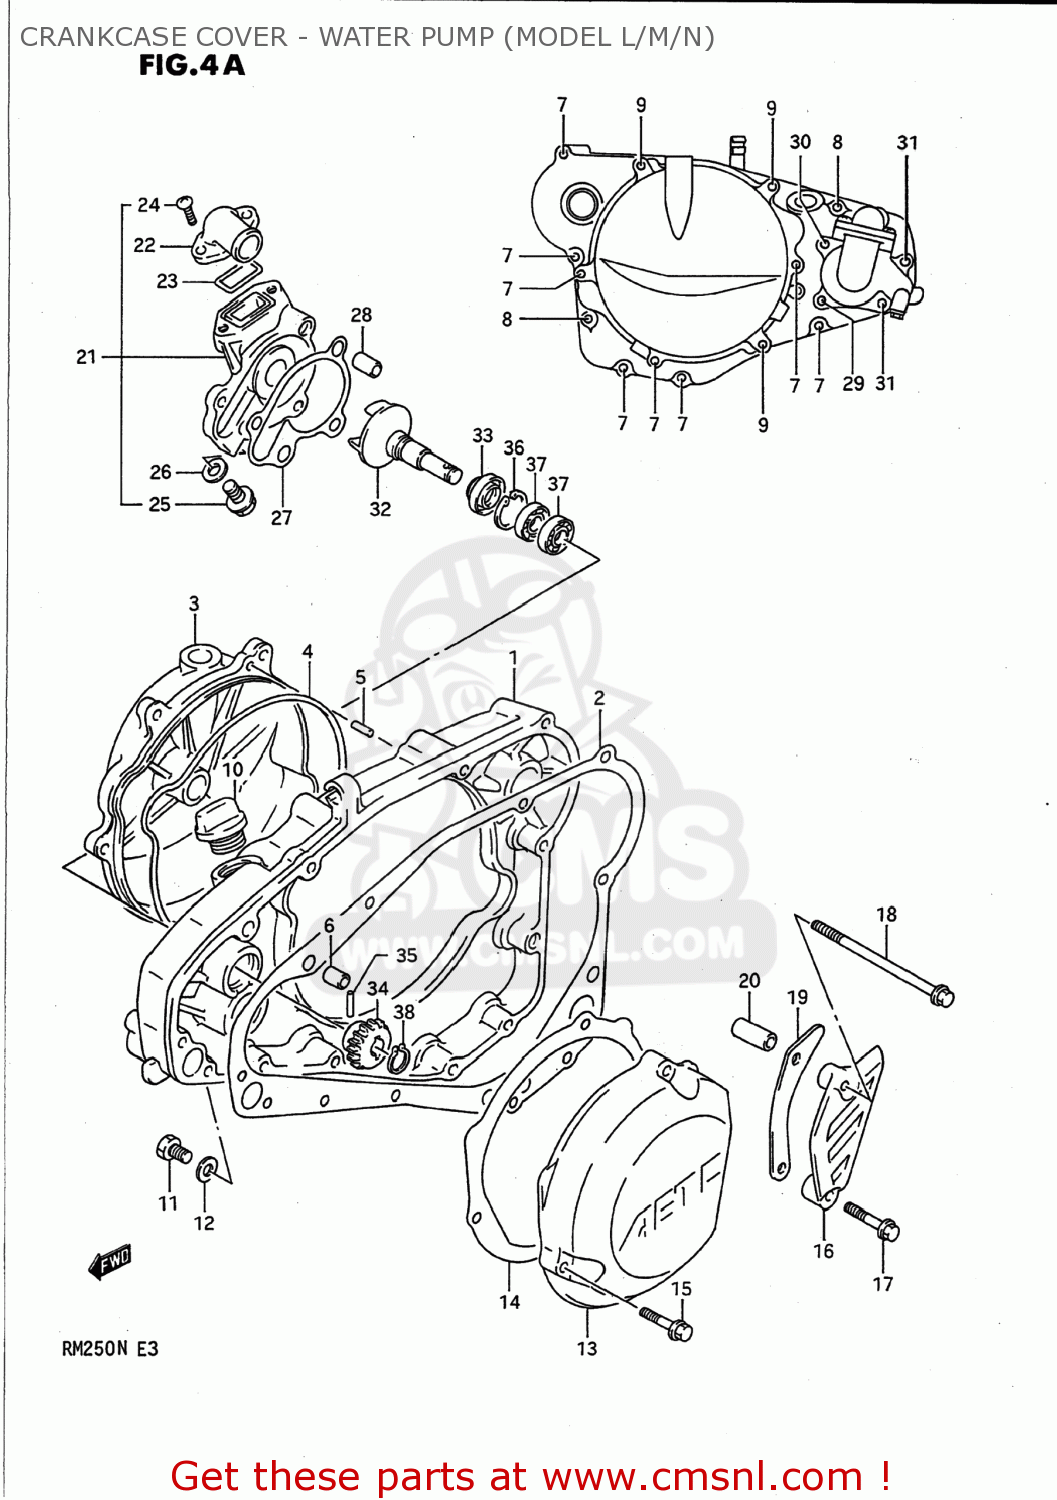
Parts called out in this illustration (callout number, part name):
1	COVER,CLUTCH
2	GASKET,CLUTCH COVER (NAS)
3	COVER,CLUTCH,OUTER
4	O RING,CLUTCH COVER OUTER
5	PIN
6	PIN
7	BOLT
8	BOLT
9	BOLT
10	PLUG SET
11	SCREW(6X10)
12	GASKET(6.2X11X1).2 (NAS)
13	COVER
14	GASKET,MAGNETO COVER (NAS)
15	BOLT
16	COVER,SPROCKET
17	BOLT
18	BOLT 6X95
19	PLATE,FR CHAIN GUIDE(13T)
20	SPACER(6.5X10.5X25)
21	CASE,WATER PUMP
22	CONNECTOR
23	O RING,WATER PUMP CONNECTOR
24	SCREW
25	BOLT,BLEEDER
26	WASHER
27	GASKET,WATER PUMP CASE (NAS)
28	PIN
29	BOLT
30	BOLT
31	BOLT
32	IMPELLER,WATER PUMP
33	SEAL,WATER PUMP OIL
34	GEAR,WATER PUMP DRIVEN
35	PIN(3X13.8)
36	CIRCLIP
37	BEARING
38	CIRCLIP
